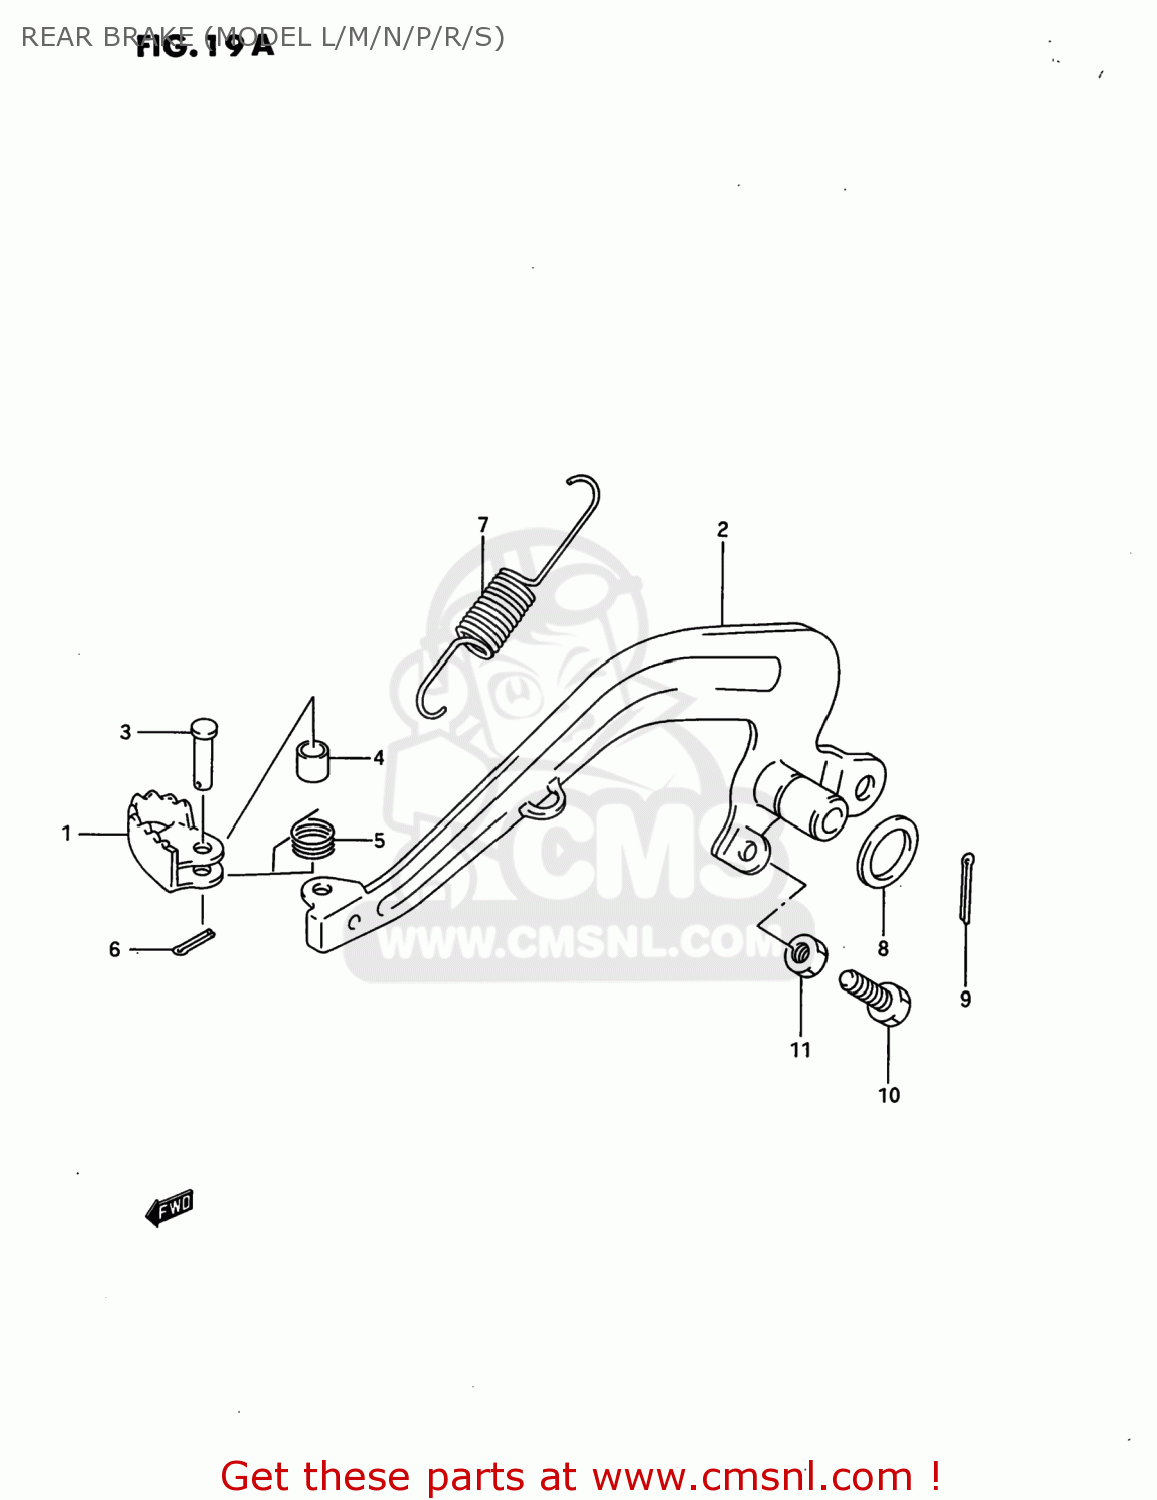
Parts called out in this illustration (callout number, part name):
1	PEDAL,BRAKE
2	ARM,BRAKE PEDAL
3	PIN
4	SPACER(9.2X9X6.5)
5	SPRING
6	PIN
7	SPRING
8	WASHER(15.5X26X2.3)
9	COTTER PIN
10	SCREW(6X23)
11	NUT 6MM
